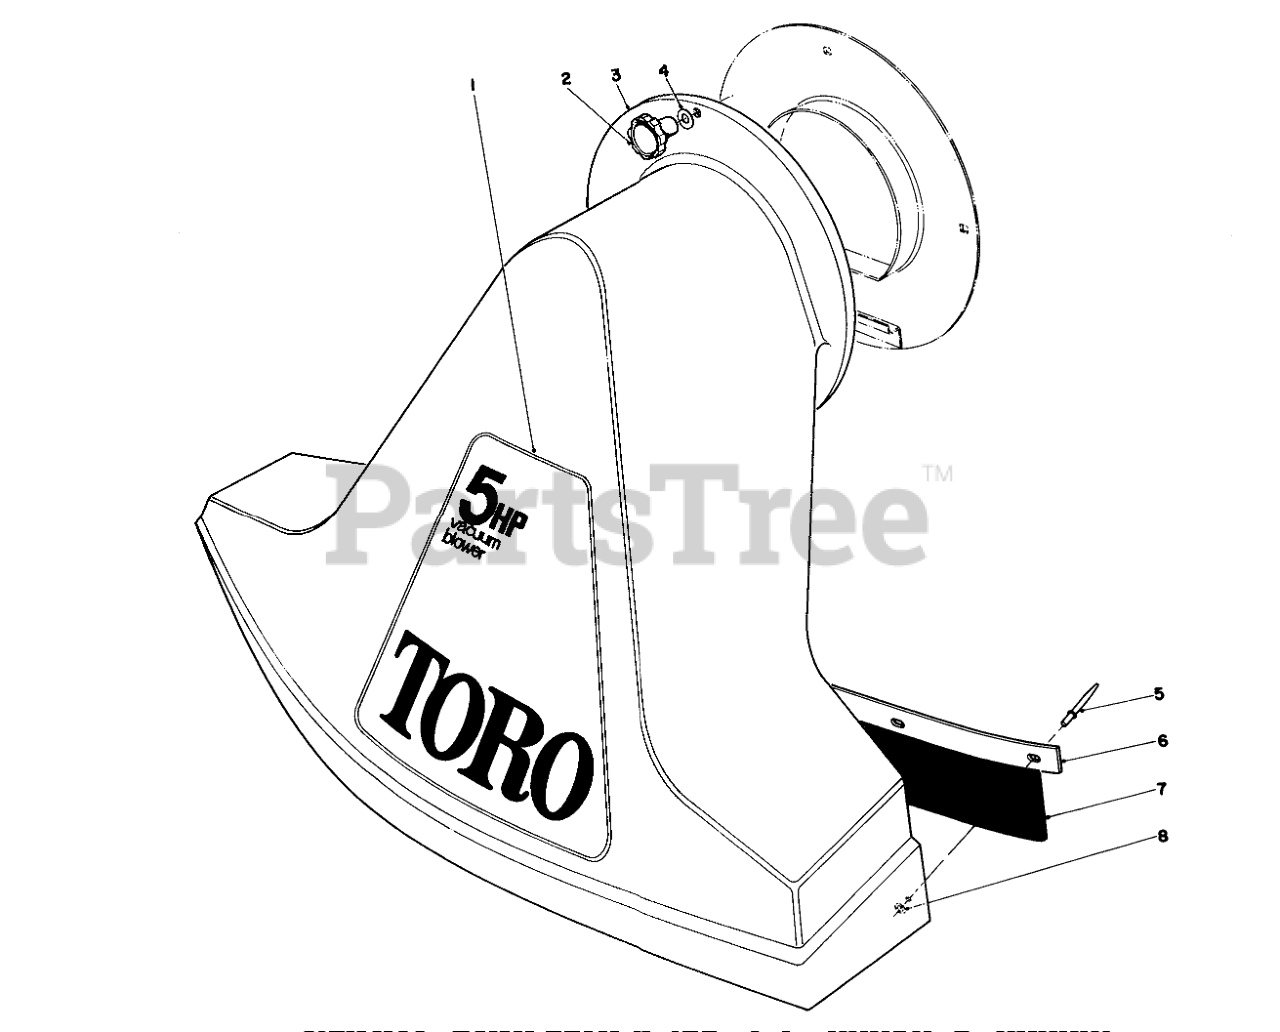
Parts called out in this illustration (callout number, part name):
1	Decal-Toro Model No. 62912
3	Snout Assembly (Incl.Ref. #5-8)
4	Washer
5	POP RIVET 3/16X.375LG
6	Clamp-Flap
7	FLAP-RUBBER
8	WASHER-FLAT
